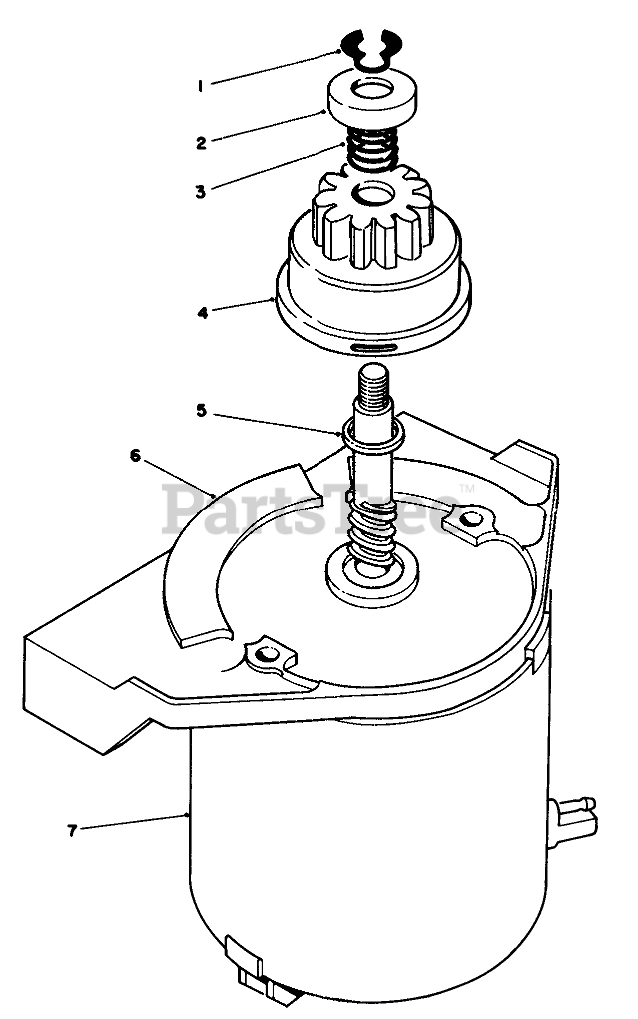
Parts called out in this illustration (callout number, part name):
1	RING-RETAINING
2	PINION STOP
3	COMPRESSION SPRING
4	PINION ASM
5	SPACER
6	END FRAME ASSY, MOTOR
7	Motor-Starter (Incl. Ref. #6)
